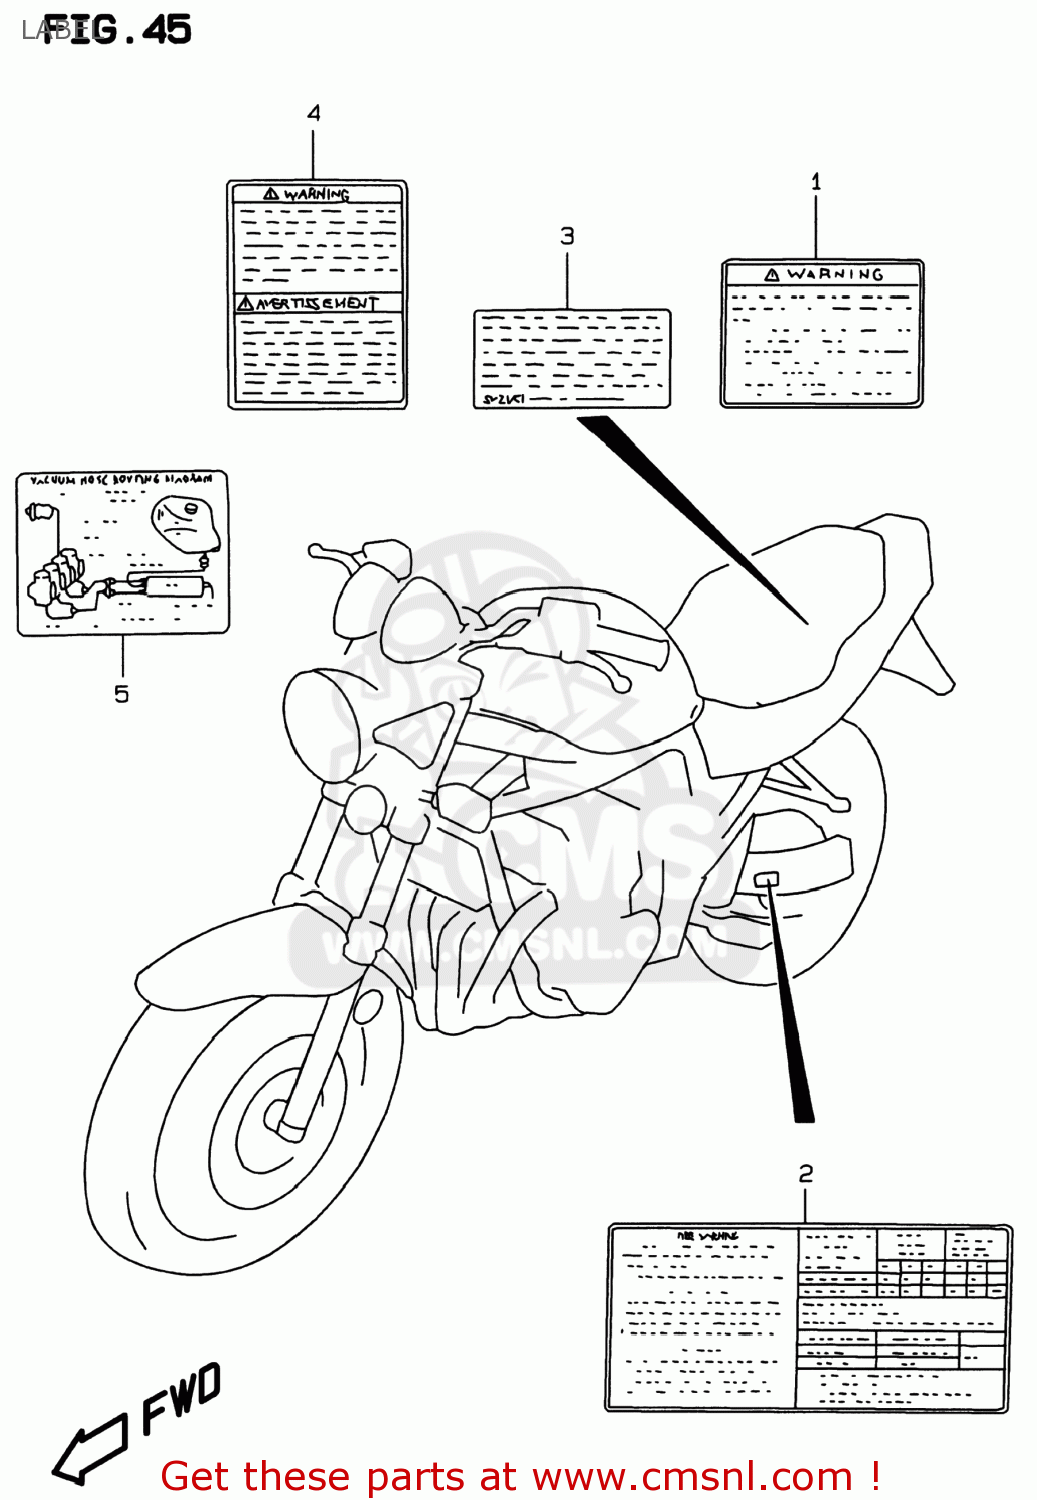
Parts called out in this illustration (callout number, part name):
1	LABEL,WARNING SAFETY
2	LABEL,TIRE AIR
3	LABEL (MANUAL NOTICE)
4	LABEL,WARNING STEERING
5	LABEL (VACUUM HOSE ROUTING)
6	MANUAL, OWNER'S
